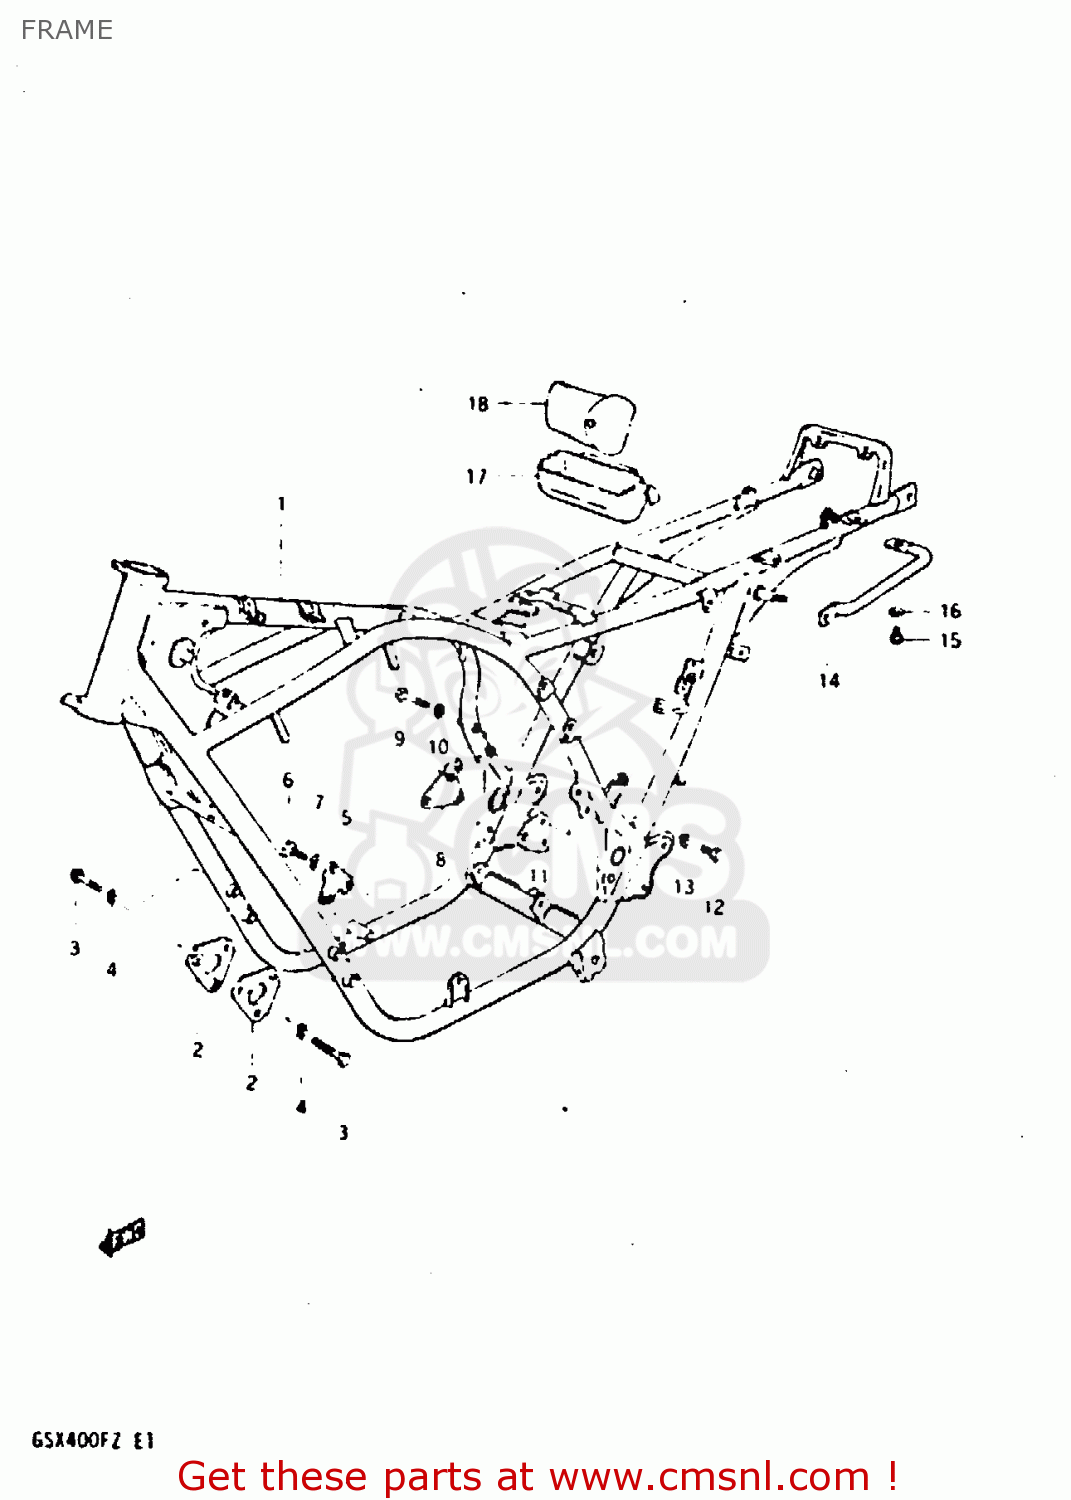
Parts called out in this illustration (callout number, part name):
1	FRAME (BLACK)
2	PLATE, NO. 1 (BLACK)
3	BOLT
4	LOCK WASHER
5	PLATE, NO. 2 RH (BLACK)
6	BOLT 8X50
7	LOCK WASHER
8	PLATE, NO. 4 RH (BLACK)
9	BOLT
10	LOCK WASHER
11	PLATE, NO.4 LH (BLACK)
12	BOLT
13	LOCK WASHER
14	GRIP, FRAME HANDLE
15	BOLT
16	WASHER
17	HOLDER, TOOL
18	TOOL SET
